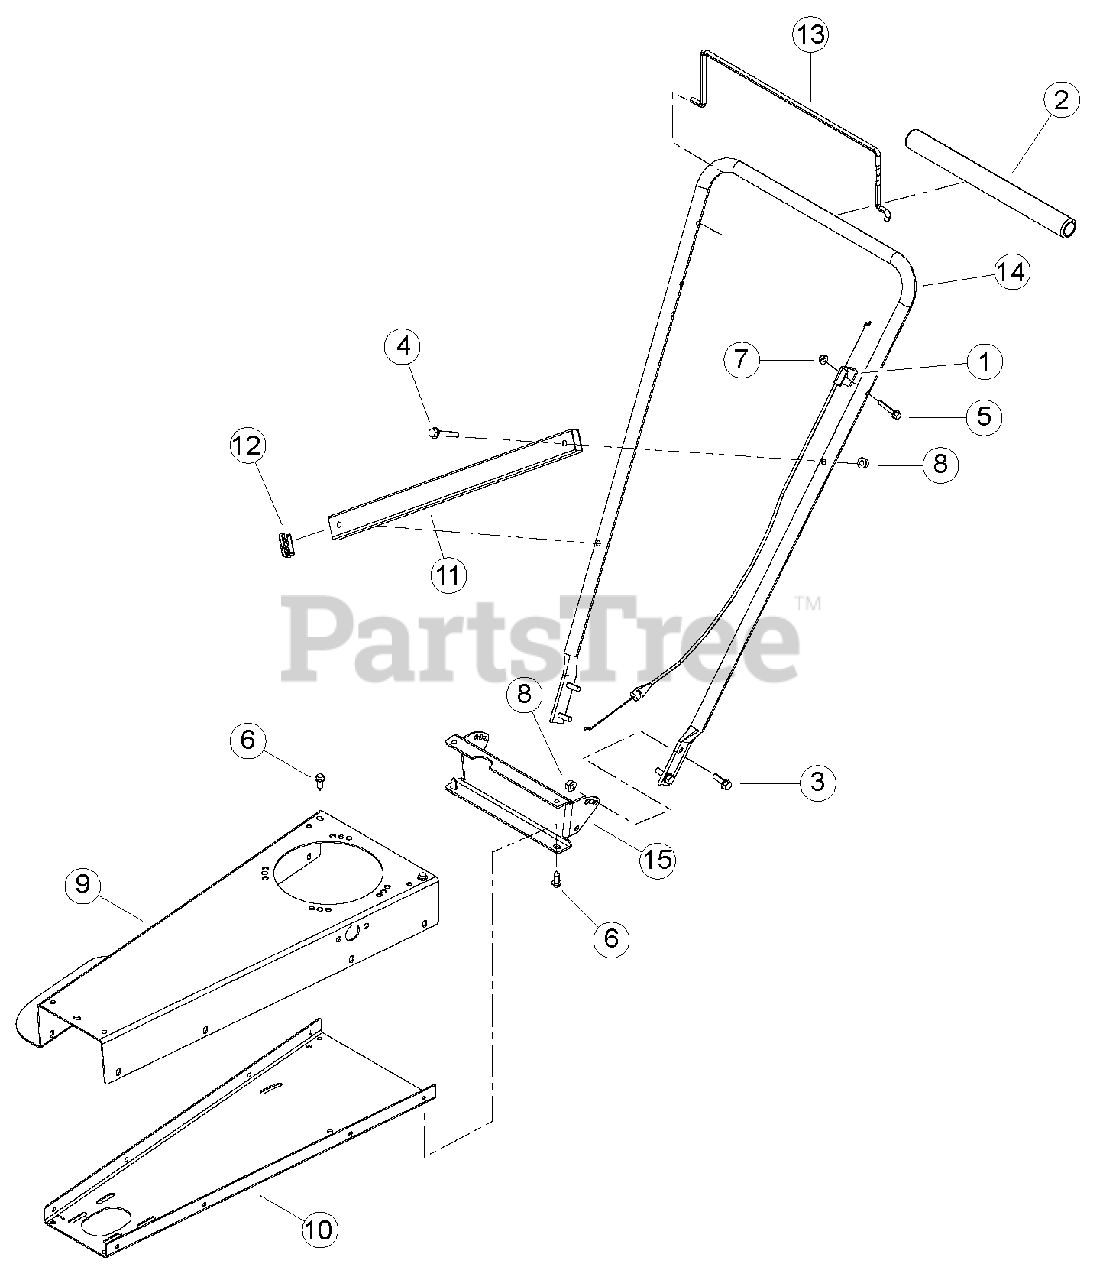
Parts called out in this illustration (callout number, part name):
1	CABLE, BRAKE CONTROL
2	PAD, FOAM HANDLEBAR
3	BOLT, 5/16 X 1 FLANGE NC
4	BOLT, 5/16 X 2-1/4 FLANGE NC
5	BOLT, 1/4 X 1-1/2 FLANGE NC
6	SCREW, 11/32 X 7/8 HWH AB THREAD ZP
7	NUT, 1/4-20 NYLOCK-FLANGE
8	NUT, 5/16-18 NYLOCK-FLANGE
9	BODY, TRIMMER STANDOFF
10	BOTTOM, TRIMMER STANDOFF
11	ASSEMBLY, WT LINE HOLDER
12	CAP, PLASTIC 3/4 X 1-1/2 TUBE
13	BAIL, TRIMMER
14	HANDLEBAR, TRIMMER
15	CHANNEL, HANDLE SUPPORT
